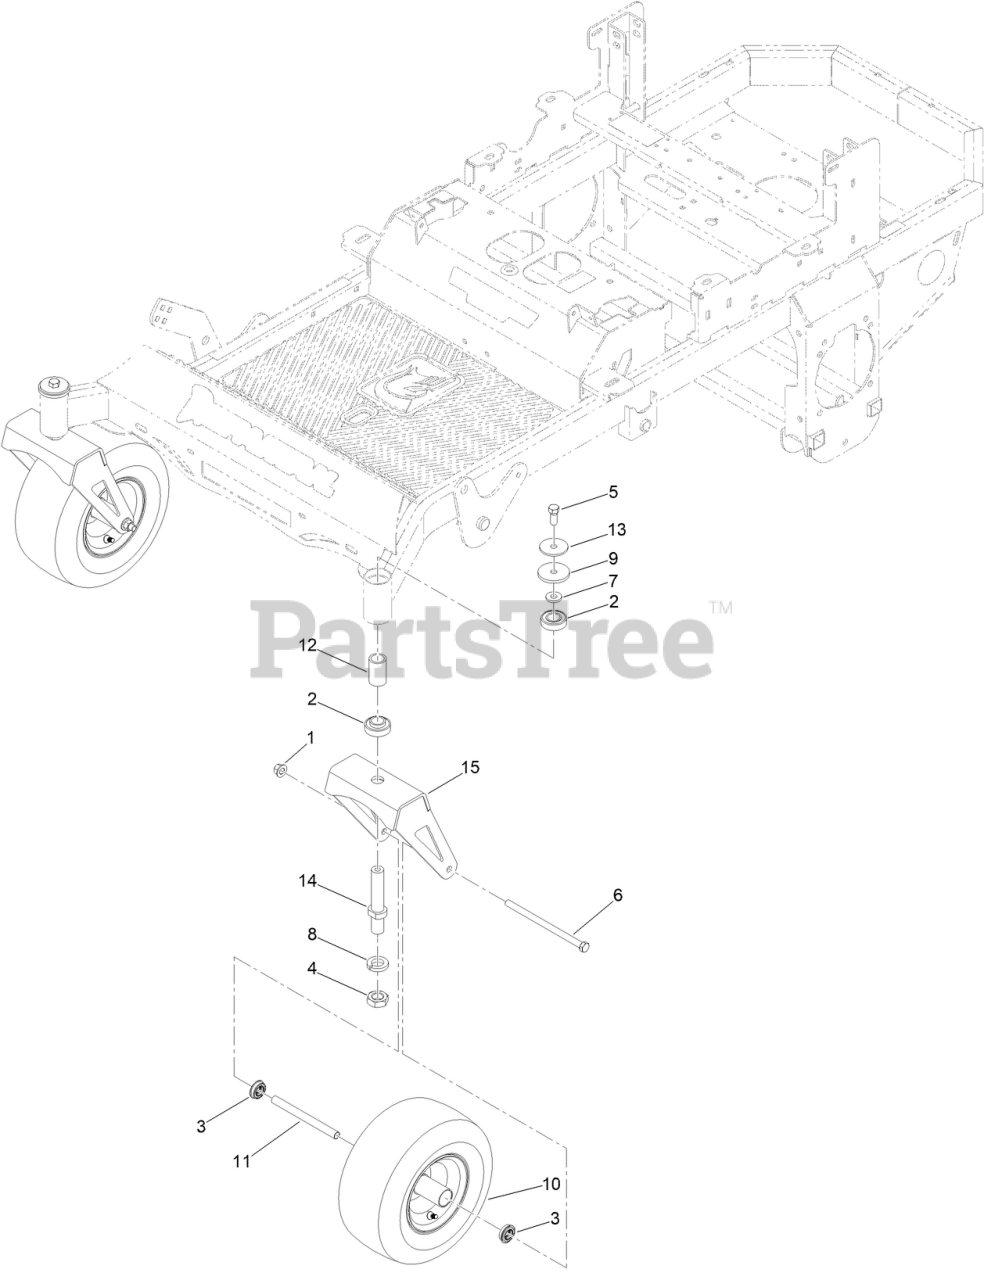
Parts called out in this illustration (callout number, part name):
1	NUT-LOCK
2	BEARING-BALL
3	RZ FT WHEEL BEARING
5	1/2-20 X 1-1/4 HEX FLANGE BOLT GR 8 YZ
6	1/2-13 X 8-1/2 HEX C/S GR 5 ZINC YELLOW
7	1/2 FENDER WASHER 1-1/4IN OD ZINC
8	1IN L/W MED SPLIT ZC
9	FT HUB PLASTIC WASHER
10	RZ/RT PRO FT TIRE ASSY-SMOOTH TREAD
11	MWR FT WHEEL SPANNER
12	CASTER FORK SHAFT BEARING SPACER
13	MWR CASTER SHAFT WASHER
14	MWR CASTER SHAFT
15	RZ CASTER FORK ASM
